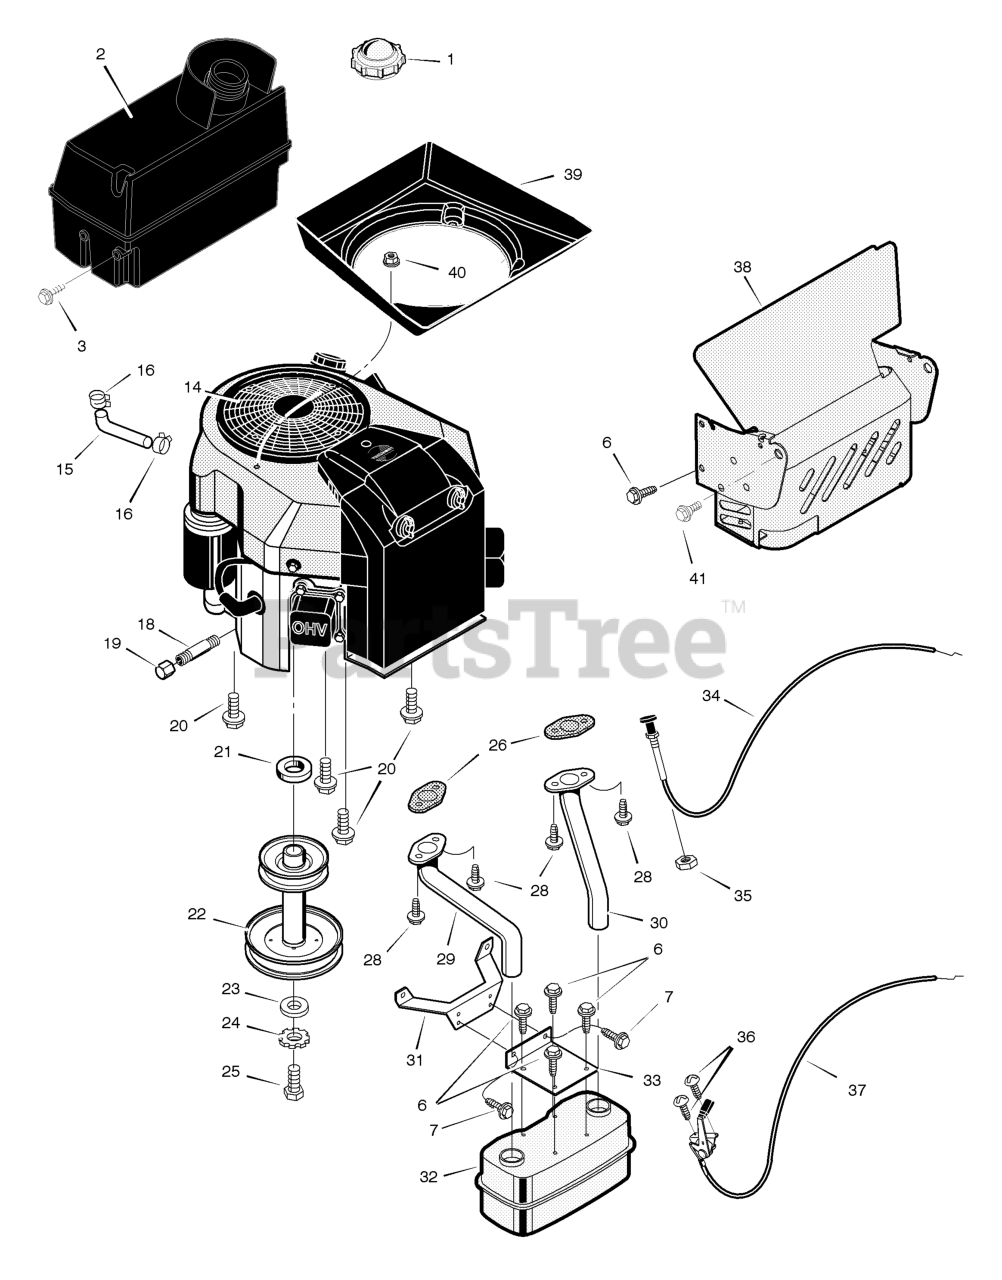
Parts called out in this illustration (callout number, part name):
1	Cap, Fuel
2	Tank, Fuel
14	Engine *
15	Fuel Line (Must cut to length)
16	Clamp
18	Pipe, Oil Drain
19	Cap, Oil Drain
20	Bolt
22	Pulley, Stack
24	Lockwasher
29	Tube, Right Exhaust
30	Tube, Left Exhaust
31	Bracket, Muffler Mount
32	Muffler
33	Bracket, Muffler
35	Nut
37	Control, Throttle
38	Shield Assembly, Heat
40	Screw
41	Bolt, Shoulder
